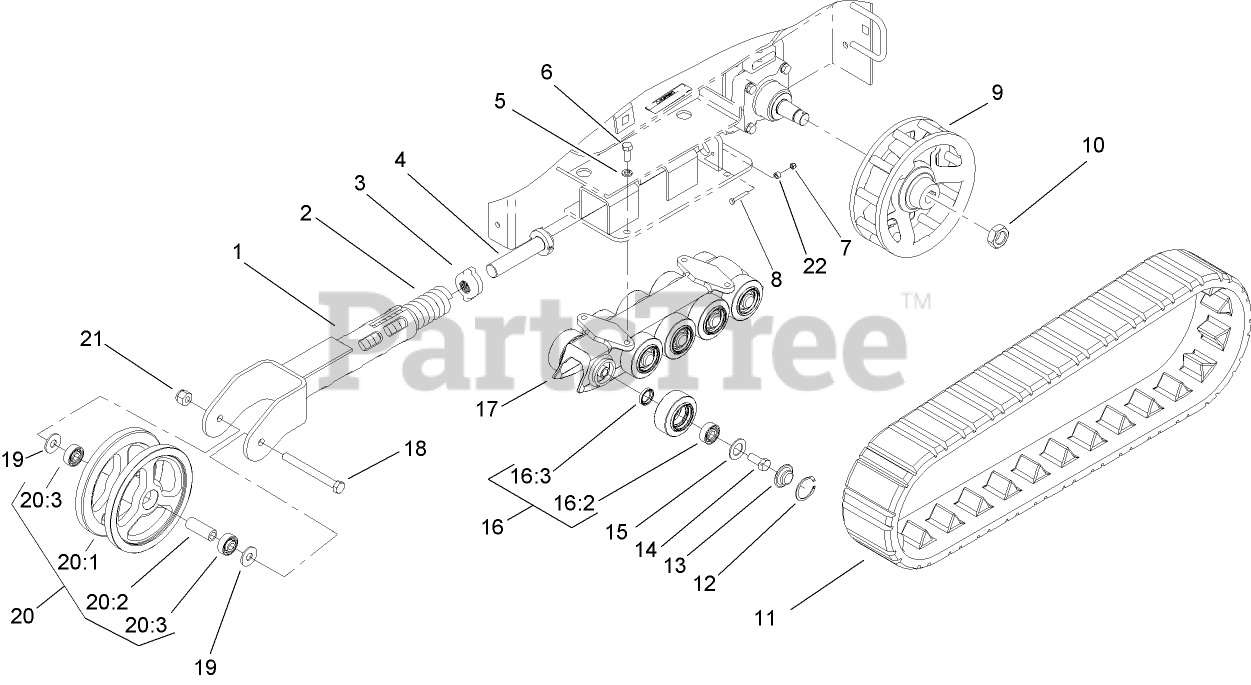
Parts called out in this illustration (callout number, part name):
1	TENSIONER ARM ASM
2	SPRING-COMPRESSION
3	BLOCK-TENSIONER
4	BOLT-TENSIONER
5	WASHER-LOCK
6	SCREW-HH
7	NUT-LOCK, NI
8	SCREW-HH
9	WHEEL-DRIVE
10	NUT-HEX
11	TRACK
12	RING-SNAP, INTERNAL
13	CAP-WHEEL, BEARING
14	SCREW-HH
15	Gasket-Bogie
16	Road Wheel ASM
16:2	BEARING
16:3	SEAL-OIL
17	GUIDE-TRACK
18	SCREW-HH
19	WASHER-FLAT
20	TENSIONER WHEEL ASM
20:1	WHEEL-TENSIONER
20:2	SPACER-WHEEL, TENSIONER
20:3	BEARING
21	NUT-HEX
22	SPACER
